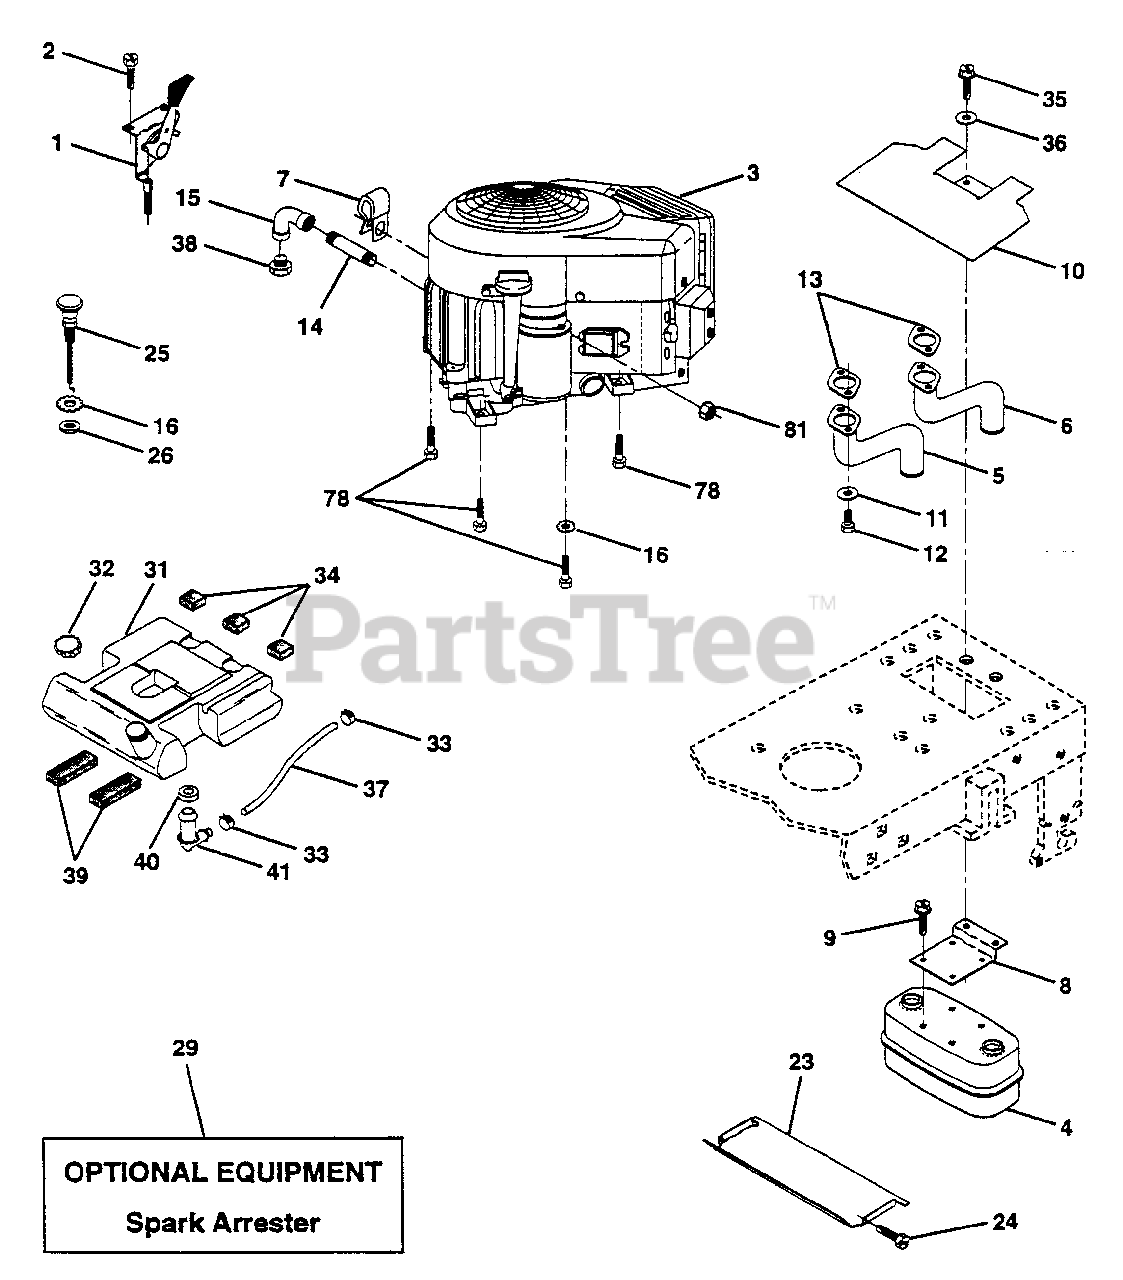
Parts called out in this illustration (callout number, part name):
1	Control RH Blk Fig 44 75
2	Screw Hex Thd Cut 1/4-20x5/8 T
4	Muffler VGT YT Dual Inlet
5	Tube Manifold LH
6	Tube Manifold RH
7	Clip Line Fuel 13/32 Mtg Hole
8	Bracket Muffler Mounting
9	Screw Hex Wsh Thd Cut 1/4-20
10	Shield Heat LT
11	Washer
12	Bolt
13	Muffler Gasket
14	Nipple Pipe 3/8 Npt X 4-1/2"
15	Elbow Std 90 Degree 3/8-18 Npt
16	Washer Lock Ext Tooth 3/8
23	Shield Heat Browning LT/YT
24	Screw Tap Hex #10-24unc X 1/2
25	Choke Control
26	Nut, Fin Hex 3/8-24 Unf
29	Kit Spark Arrestor (Flat Scrn)
31	Tank Fuel 3 50 Rear
32	Cap Asm Fuel
33	Clamp Hose Blk
34	Pad, Spacer
35	Screw Thdrol 5/16-18 x 3/4
36	Washer 13/32 x 1-1/4 x 12 Ga.
37	Line Fuel 54"
38	Plug Oil Drain
39	Pad, Idler
40	Bushing
41	Stem Tank Fuel
78	Screw Thdrol 3/8-16 x 1-1/4
81	Nut Keps Hex 1/4-20 UNC
